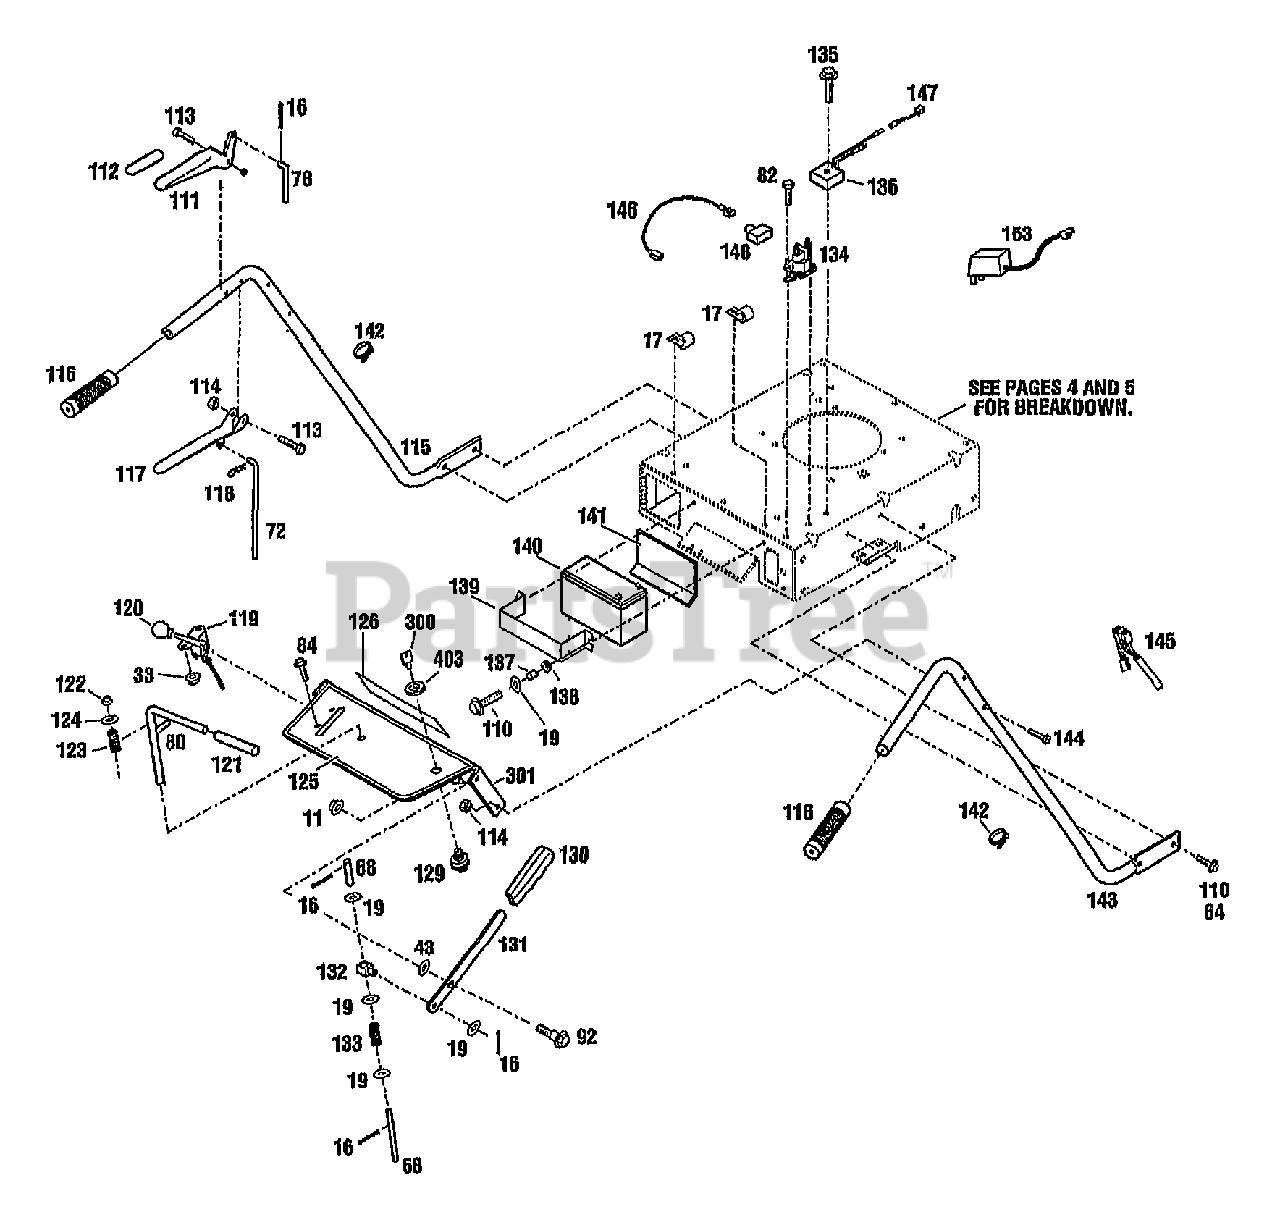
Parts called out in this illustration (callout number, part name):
11	NUT-HFLK 3/8-16 ZP
16	PIN-COTTER .093X.625
17	CLIP-J
19	WASHER-FLAT 5/16 SAE
33	NUT-HF/LK 1/4-20 ZP
43	WASHER-FLAT 1.0X.516X.031
64	NUT-HFLK 5/16-18 ZP
68	ROD-UPPER BLADE
72	ROD-UPPER TRANS MOWER
78	ROD-UPPER BRAKE
80	ASSM-SHIFT LEVER
82	SCR 1/4-20X.5 FL SELF TAP {34041}
84	SCR-HFLK 1/4-20X.50 ZP
92	BOLT-SHOULDER MOWER
110	SCR-HFLK 5/16-18X.75 ZP
111	KIT-HANDLE ASSM
112	DECAL-OPC MOWERS
113	SCR-HH 1/4-20X1.5 G5ZP
114	NUT-HT LK 1/4-20
115	HANDLEBAR-LH
116	GRIP-FLEX
117	HANDLE-CONTROL MOWER
118	PIN-CLIP .08
119	CABLE-THROTTLE CONTROL
120	KNOB
121	GRIP-HANDLE
122	BUSHING-.5X.21 NYLON FLNG
123	SPRING
124	WASHER-1.06X.531X.1 ZP
125	DECAL-WARNING STD WC {34044}
125	DECAL-WARNING ELEC WC {34041}
126	DECAL-WIDE CUT T/B
129	ASSM-KEYSWITCH {34041}
130	GRIP-HANDLE
131	LEVER-MOWER ENGAGE ZP
132	BLOCK-PIVOT
133	SPRING-COMPRESSION
134	SOLENOID {34041}
135	SCR-HFLK {34041}
136	REGULATOR
137	SPACER {34041}
138	GROMMET {34041}
139	BRACKET-BATTERY {34041}
140	BATTERY {34041}
141	PAD-BATTERY {34041}
142	TIE-CABLE NYLON BLACK
143	HANDLEBAR-RH
144	SCR-HH 1/4-20X1.75 G5 ZP
145	HARNESS-WIRING {34041}
146	ASSM-WIRE LEAD {34041}
147	ADAPTER-HARNESS {34041}
148	BOOT-CABLE {34041}
153	CHARGER-BATTERY {34041}
300	KEY-IGNITION {34041}
301	ASSM-CONSOLE {34044} (INCL. 125)
301	ASSM-CONSOLE {34041}
403	NUT-IGNITION SWITCH
